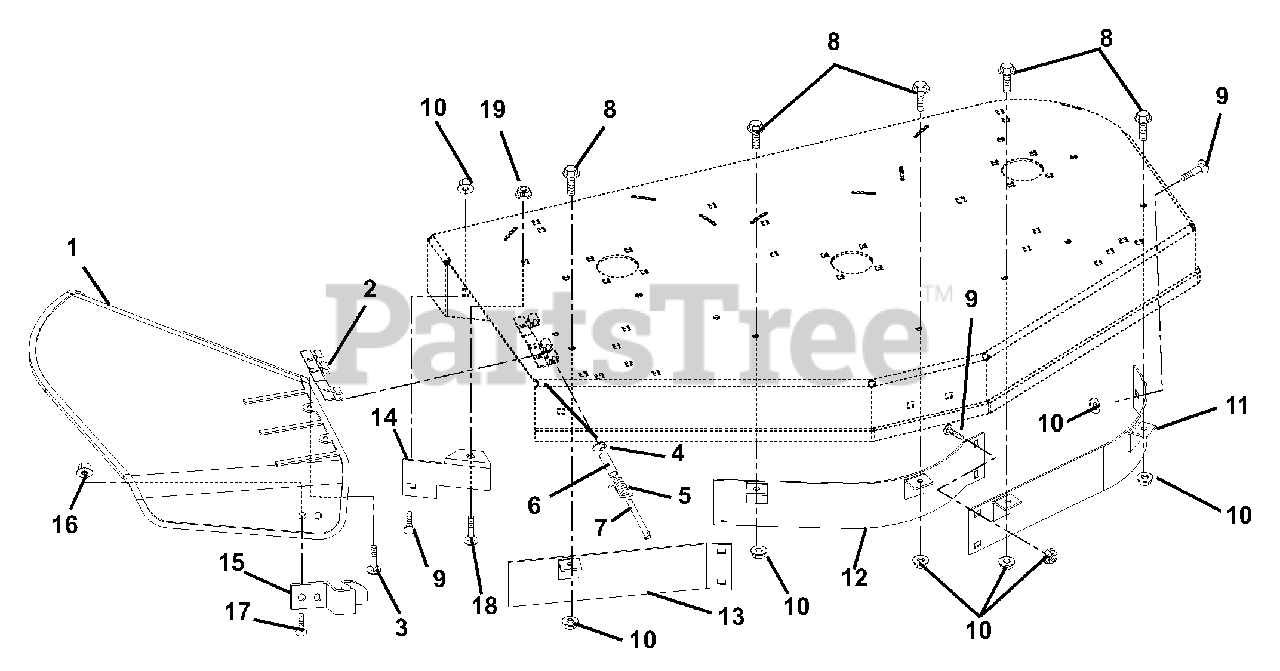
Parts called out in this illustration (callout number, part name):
1	DEFLECTOR, CHUTE
2	HINGE PLATE
3	@BLT-RDHDSQNK .25-20X.75 G5YZ
4	RG-RTNG-EXT .312X.025
5	SG-TORS .095X.50X 1.0
6	BSHG-SLV .334 X .502 X 1.437
8	BLT-SERHFWH .312-18X.75 YWZC
9	@BLT-RHDSSQNK .31-18X.75 G5YZ
10	@NUT-LK-NYL-FLG .31-18 YWZC
11	BAFFLE - LEFT FRONT - 40"
12	BAFFLE - CENTER FRONT - 40"
13	BAFFLE - RIGHT FRONT - 40"
14	DEFLECTOR-40"
15	FLAT SPRING
16	@NUT-LK-TOP-FLG .25-20 YWZC
17	@BLT-RDHDSQNK .25-20X.50 G5YZ
18	@BLT-RDHDSQNK .38-16X1.00 G5YZ
19	@NUT-LK-NYL-FLG .38-16 YWZC
